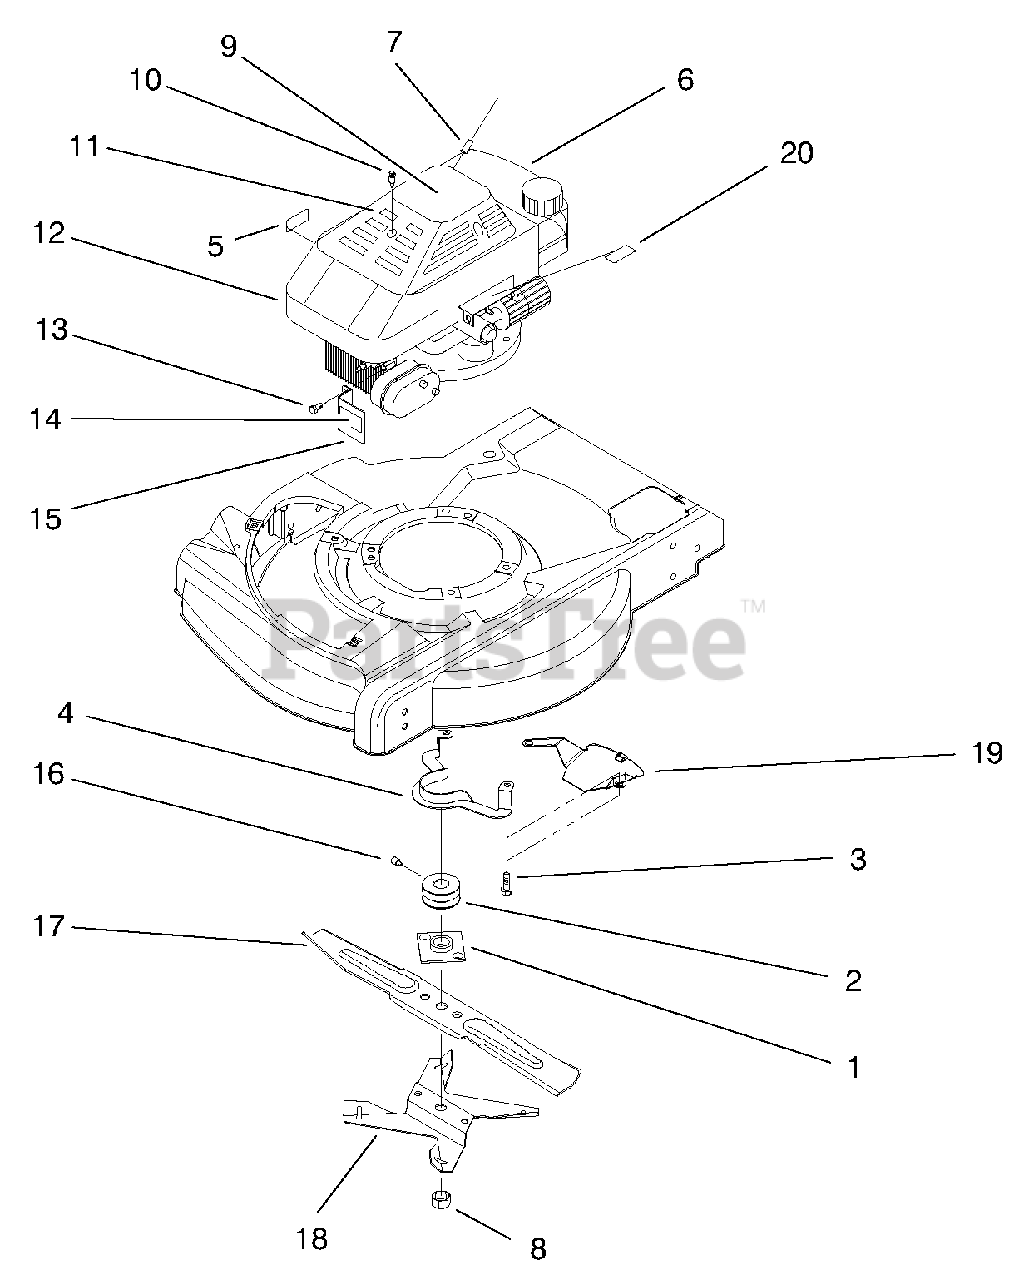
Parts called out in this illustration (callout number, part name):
1	ASM-Plate & Collar
2	Pulley-Engine
3	Screw-Engine Mount
4	Guide-Belt
5	Decal-Oil Instruction
6	ASM-Engine
7	Rope-Stop
8	Nut-Blade
9	Decal-Recoil
10	Screw-Recoil Cover
11	Cover-Starter
12	Shroud-Engine
14	Decal-Warning
15	Guard-Muffler (Incl. Ref. #14)
16	Screw-Set
17	Blade-21" Whirl
18	Fan-Mulching
19	Shield-Grass
20	Decal-Primer
